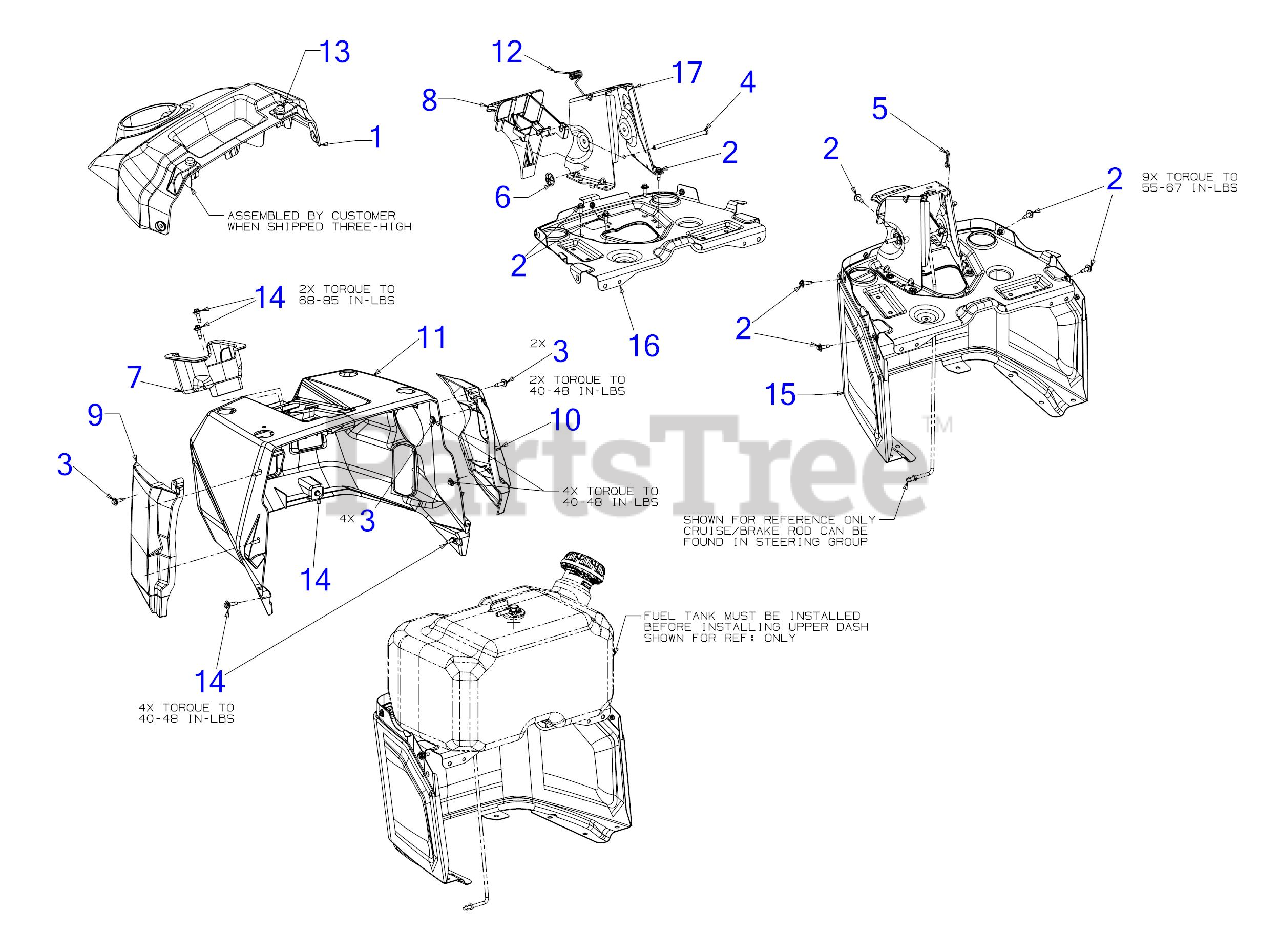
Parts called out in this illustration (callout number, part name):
1	UPPER DASH CAP
2	SCREW M6-1 x .625
3	SCREW 1/4-10 x .750
4	HINGE PIN .25 x 4.50
5	BOW TIE COTTER PIN 1/4-5/16
6	PUSH ON NUT
7	STEERING SHAFT BEARING
8	CRUISE/BRAKE DASH LEVER
9	DASH SIDE CAP (RH)
10	DASH SIDE CAP (LH)
11	UPPER DASH CAP (CRAFTSMAN)
12	TORSION SPRING .330 ID
13	BUMPER, .62 DIA x .3
14	SHOULDER SCREW M6-1 .368 X.115
16	DASH/FUEL TANK PLATE
17	STEERING MOUNT BRACKET
